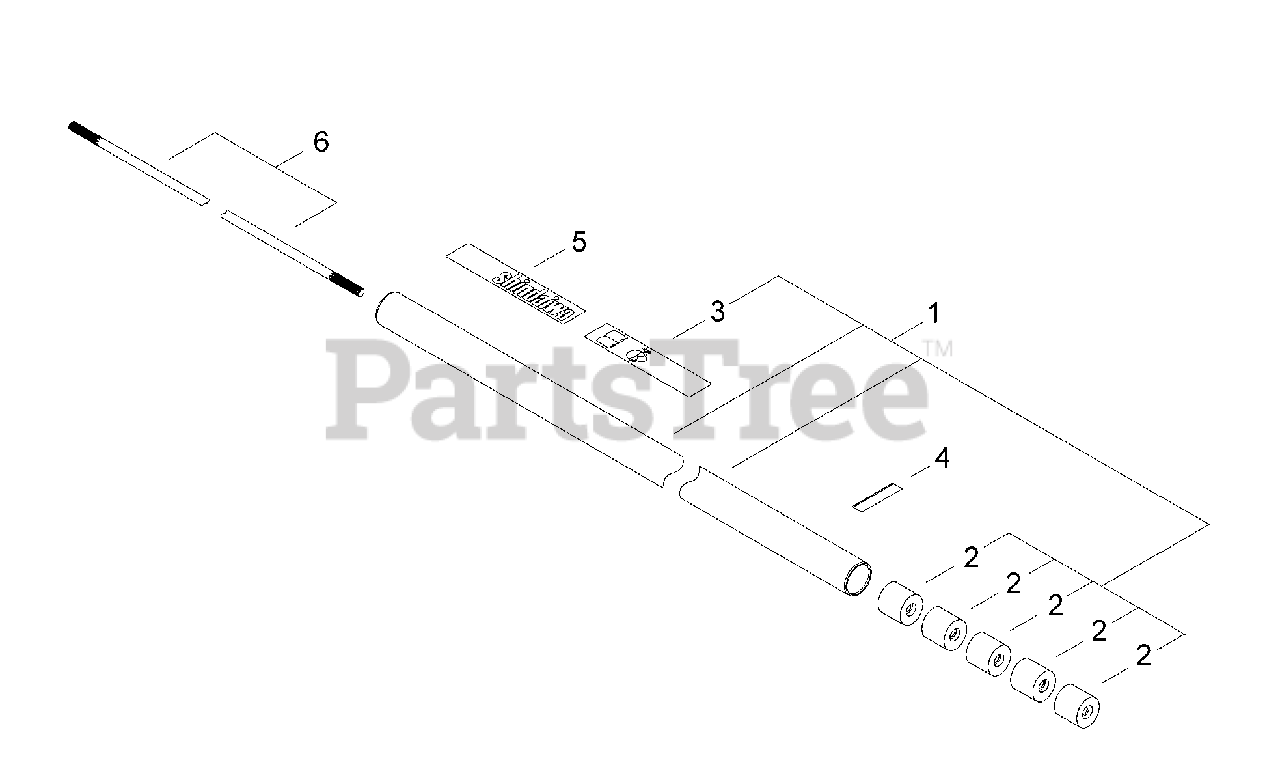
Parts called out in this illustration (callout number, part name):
1	MAIN PIPE ASSY
2	BUSHING
3	LABEL - CAUTION
4	LABEL - INSTRUCTION
5	LABEL - TRADE
6	PIPE, MAIN
